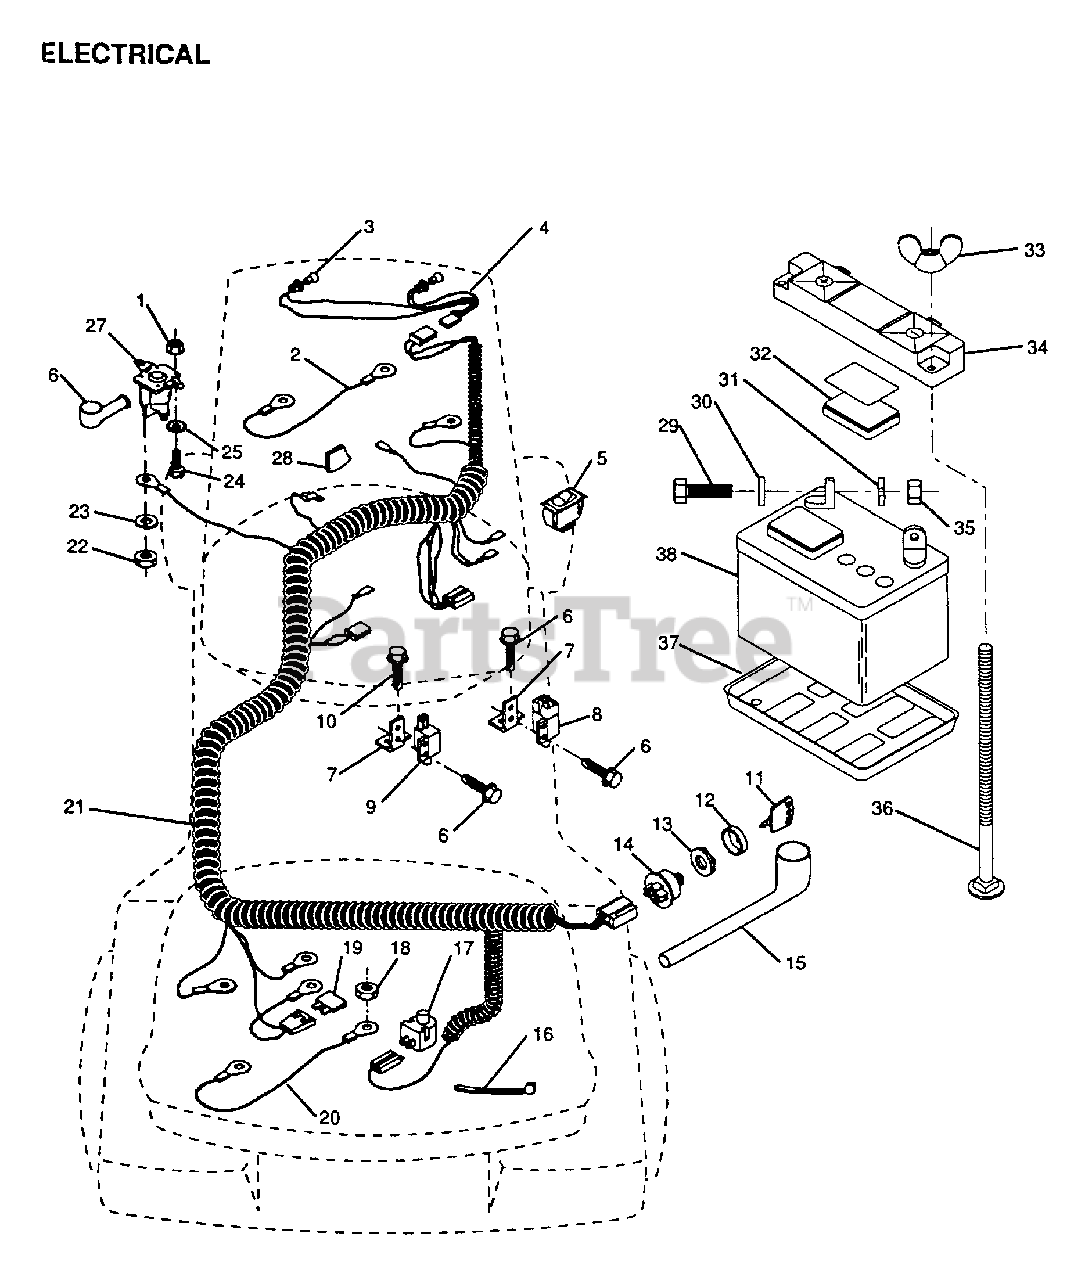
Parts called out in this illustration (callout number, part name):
1	NUT
2	CABLE LTV
4	HARNESS T
5	SWITCH LT
6	SCREW
7	BRACKET LT
8	SWITCH-INTER. GT
9	SWITCH INTERLOCKT
10	SCREW
11	KEY
13	NUT IGNITION
15	COVER IGNITION SW
16	WIRE TIE
17	SWITCH SEAT
19	FUSE HYT
21	HARNESS IGNITION
22	NUT
24	BOLT
28	STOP PLASTIC
29	BOLT LT
30	WASHER
31	LOCKWASHER
32	"CAP,BATTERY "
36	BOLT
37	"TRAY T, BATTERY"
